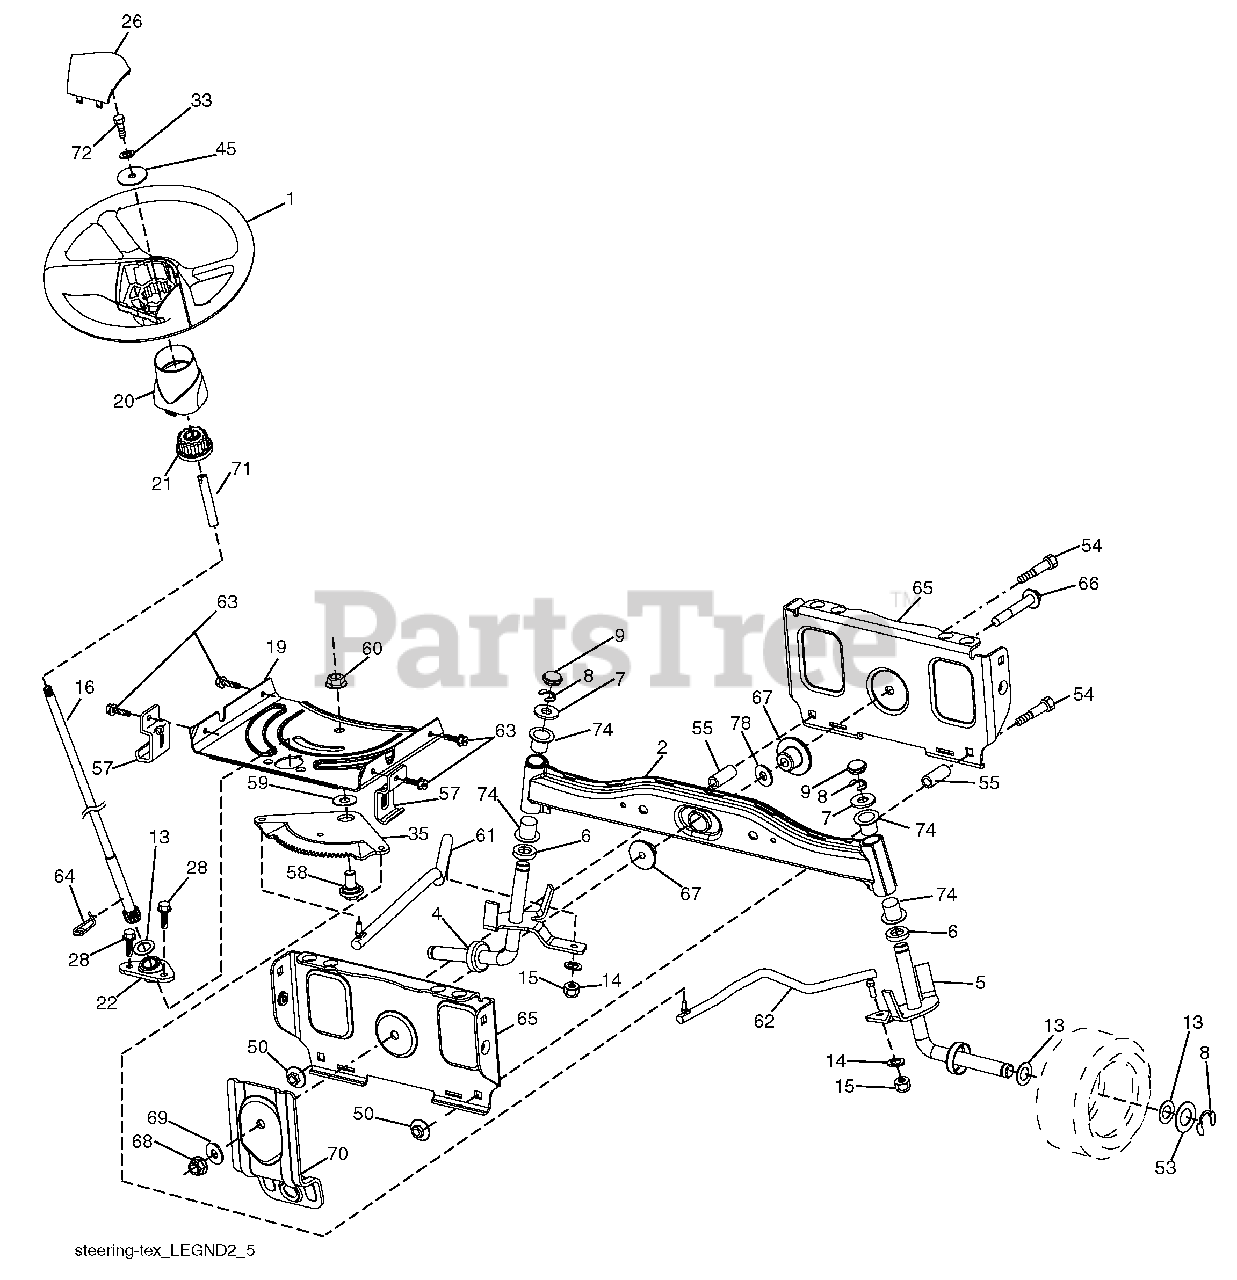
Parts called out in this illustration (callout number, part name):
1	Wheel, Steering
2	Axle Asm., Front
4	Spindle Asm., LH
5	Spindle Asm., RH
6	Bearing, Race Thrust Harden
7	Washer 25/32 x 1-5/8 x 16 Ga.
8	Ring, Klip #T5304-75
9	Cap, Spindle
13	Washer 25/32 x 1-1/4 x 16 Ga.
14	Washer Lock 3/8
15	Nut, Crown Lock 3/8-24 unf
16	Shaft Steering
19	Plate Steering
20	Boot, Steering
21	Adapter, Wheel Steering
22	Bushing, Strg. Blk
26	Insert, Wheel Steering
28	Screw 3/8-16 x 3/4
33	Washer Lock 5/16
35	Gear, Sector Plate
45	Washer 11/32 x 2-3/8 x 12 Ga.
50	Nut Lock Flg 3/8-16 unc
53	Washer Hardened .793 x 1.637 x .060
54	Bolt Hex HS 3/8-16 unc x 2-1/4
55	Spacer Brace Axle
57	Bracket Upstop
58	Bolt Shoulder Sector Pivot CFM
59	Washer Thrust Sector Steering
60	Nut Flange Lock 5/8-11
61	Draglink LH
62	Draglink, RH
63	Screw 5/16-18 x 3/4
64	Retainer Clip Spring Steering
65	Brace Axle Front
66	Bolt Hex Fghd 7/16-14 x 3 Serr
67	Bushing PM Front Axle
68	Nut Lock Flange 7/16-14 Gr. 5
69	Washer 1.5 x .505 x .118
70	Bracket Deck Susp. Front
71	Shaft Ext. Steering
72	Bolt 5/16-18 x 4.5 Gr. 5
74	Bearing Col Strg.
78	Washer Thrust .515 x .750 x .033
